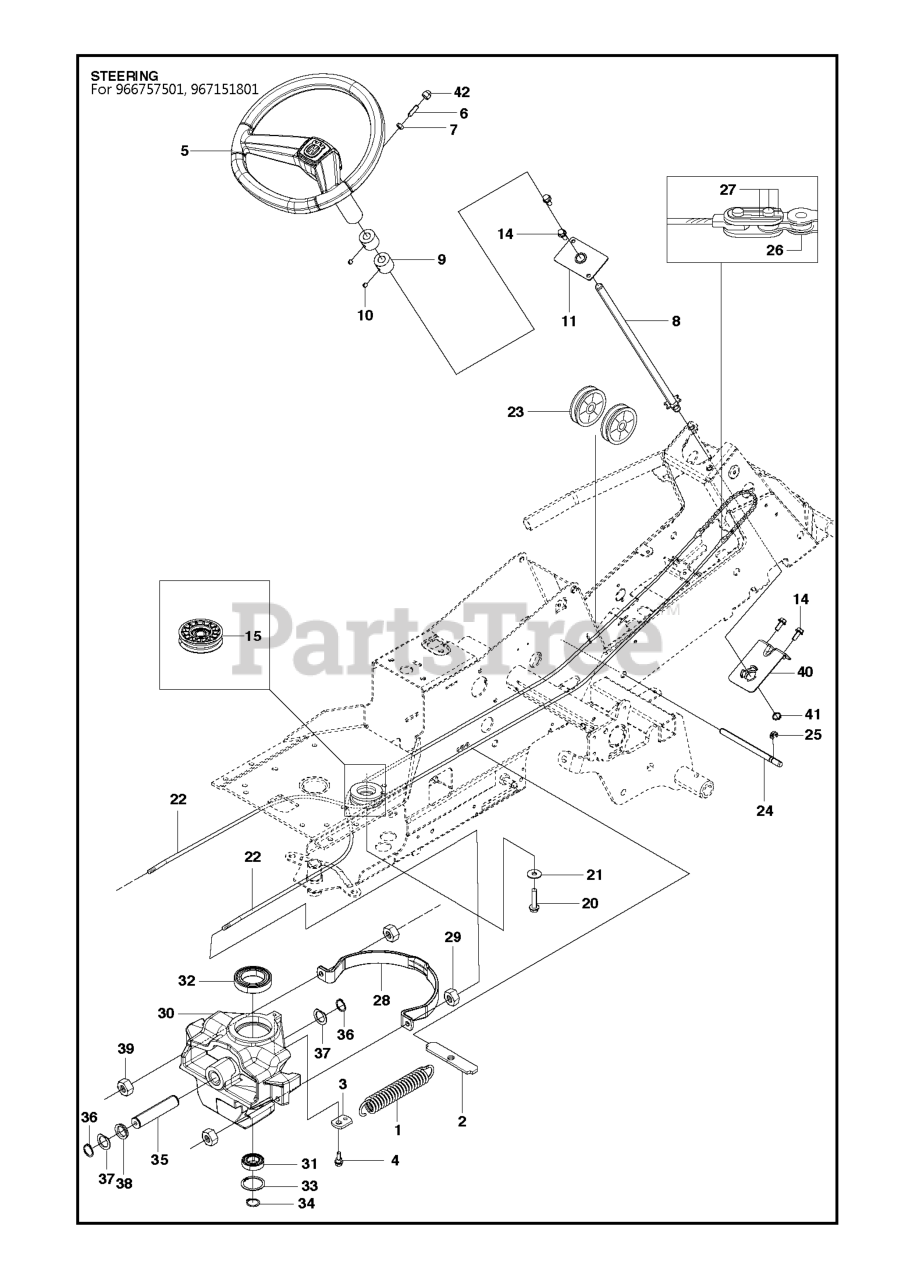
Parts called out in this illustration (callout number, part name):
2	SPRING BRACKET
5	STEERING WHEEL
7	NUT
8	STEERING ROD ASSY LONG
9	SPACER
11	BRACKET STEERING ASSY WITH BUS
20	COLLAR SCREW
22	WIRE ASSY
24	SHAFT
25	RETAINING RING
26	STEERING CHAIN
28	WIRE GUIDE
31	Ball Bearing 6005-2rs
32	BALL BEARING 6010 2RS1
33	CIRCLIP SGH 47
34	RETAINING RING SGA 25
36	RETAINING RING SGA 25
39	NUT
40	BRACKET STEERING ROD ASSY
41	RETAINING RING SGA 15
42	PROTECTIVE COVER
